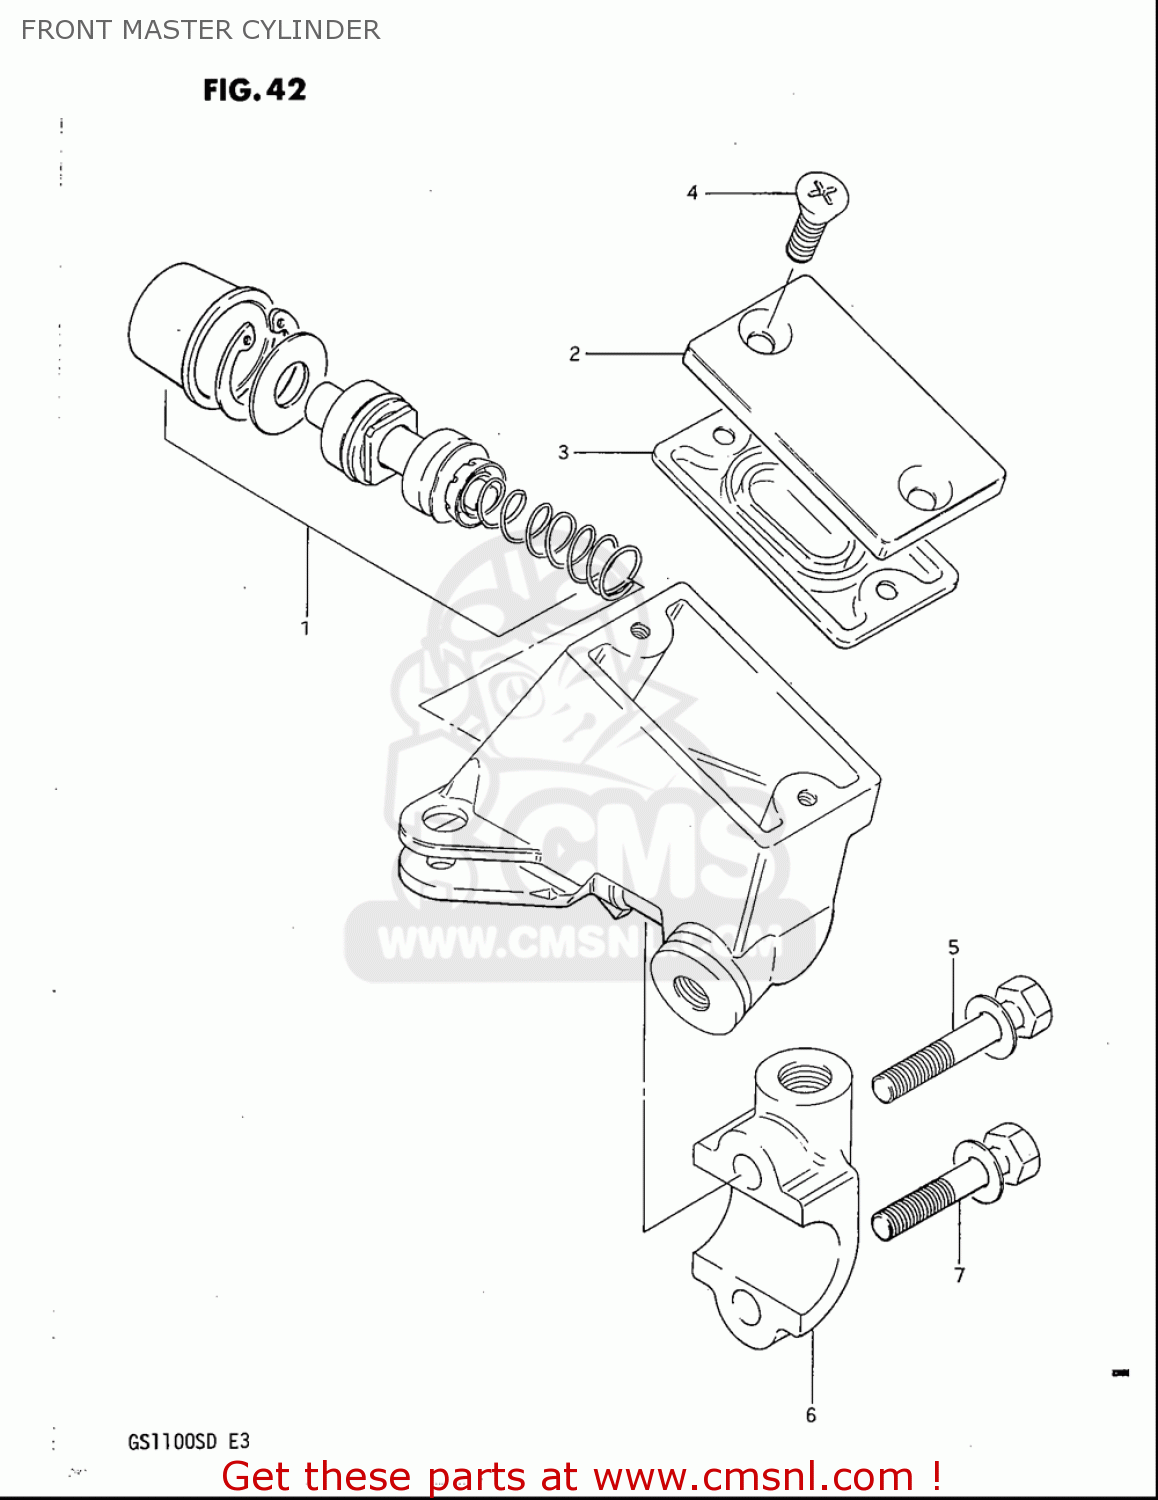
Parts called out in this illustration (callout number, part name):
1	PISTON & CUP SET
3	DIAPHRAGM
4	SCREW
5	BOLT,MASTER CYLINDER H
6	HOLDER
7	BOLT,MASTER CYLINDER H
